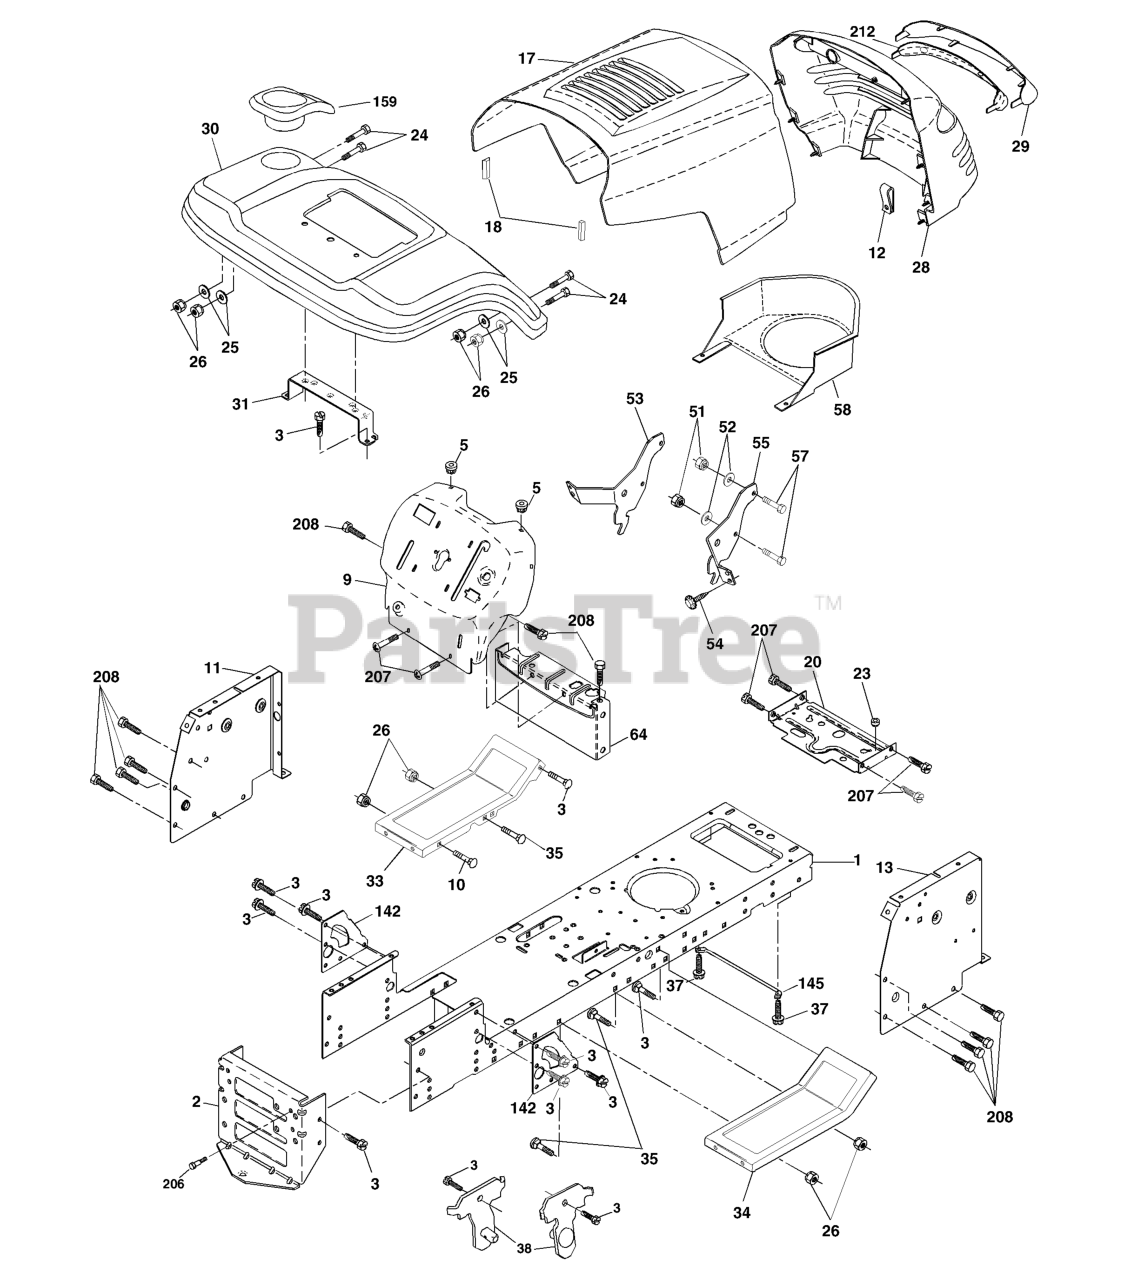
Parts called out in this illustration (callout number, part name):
2	DRAWBAR
3	SCREW 3/8-16X3/4
5	BUMPER.RUBBER.HOOD
9	DASH SLKSCR
10	BOLT D
11	PANEL DASH LH
13	PANEL ASM, DASH RH
17	HOOD ASM.
18	BUMPER HOOD T
20	PLATE MTG
23	BUSHING.SNAP.NYL.BLK.
24	BOLT
25	WASHER
26	NUT
28	GRILLE ASM
29	LENS
31	BRACKET FENDER
33	FOOT REST LH
34	FOOTREST RH
35	BOLT
37	Screw Thdrol 6/16-18 x 1/2 TYT
38	BRACKET
51	LOCKNUT.NYLOC.1/4-20
52	WASHER
53	BRACKET.GRILLE.LH
54	SCREW.HEX.WS.HD.8-18 X 7/8
57	BOLT
58	AIR DUCT P/L/LT
64	DASH LOWER
142	PLATE
145	ROD PIVOT CHASSIS/HOOD
159	CUPHOLDER
206	SHOULDER BOLT 5/16-18TT
207	SCREW, 5/16-18 X 1/2
208	SCREW 3/8-16X1/2
212	REPL BY 532 1745-03
